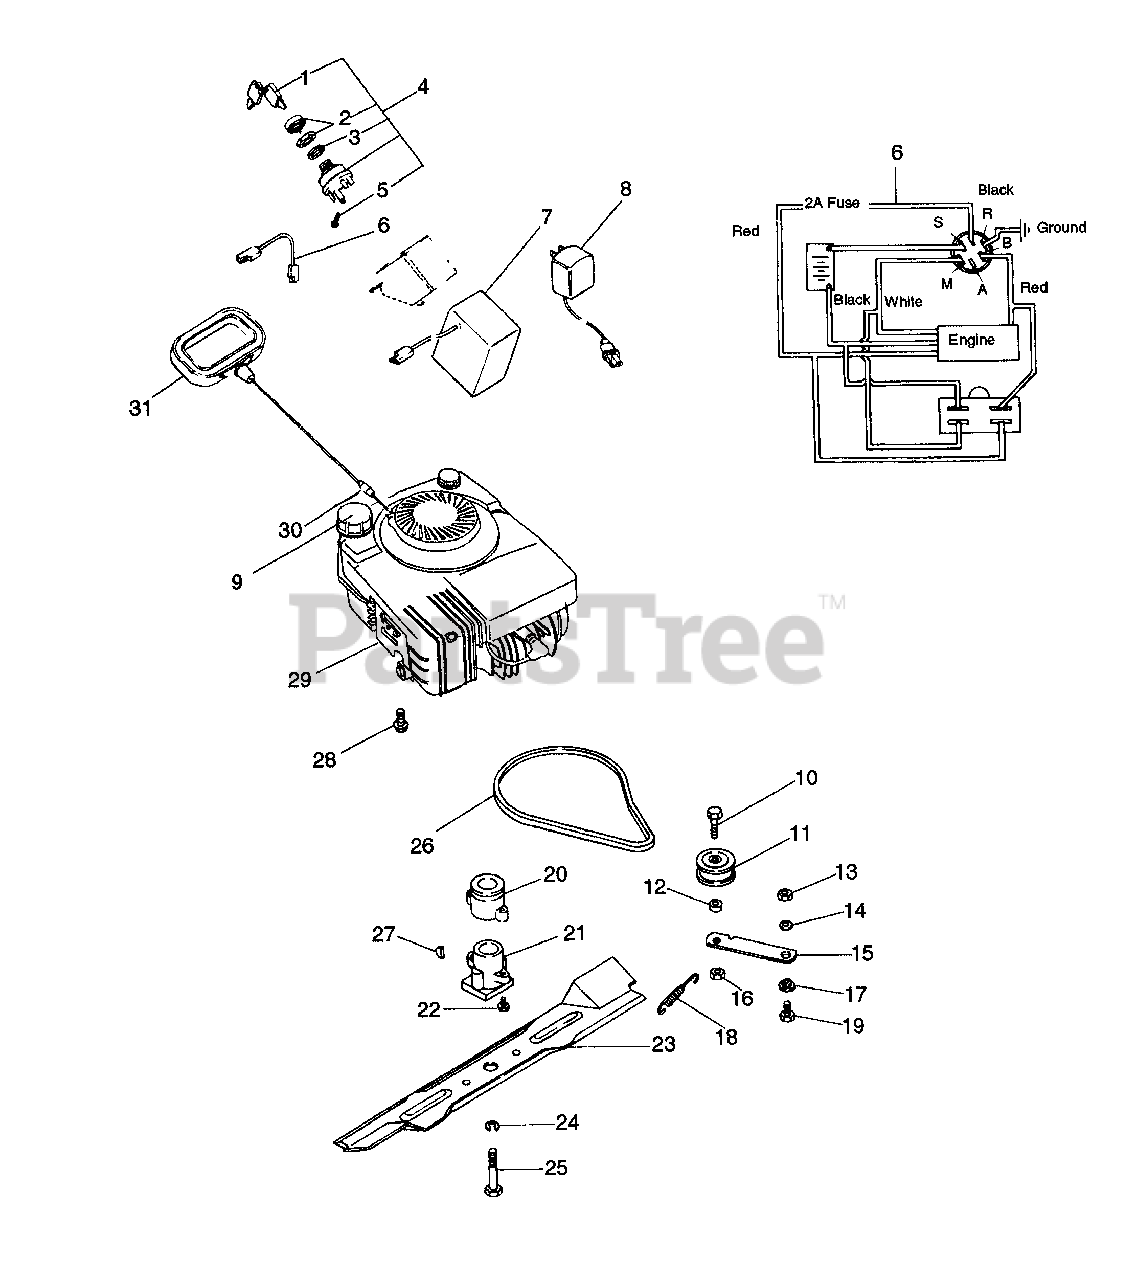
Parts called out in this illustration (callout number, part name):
1	KEY SET
2	NUT-PANEL .625-32 GRECO
2	CAP - IGNITION SWITCH
2	NUT .812-20 PL
3	WSHR-LK-INT .625X.045 PL
3	WSHR-LK-INT .813X.020 PL
4	KEY SWITCH
5	SCR-MCH 10-32X.32 SLRH PL
6	WIRE HARNESS
7	BATTERY
8	BATTERY CHARGER
9	FUEL CAP
10	BLT-HEX .44-14X1.25 PL GR2
11	IDLER-FLAT 1.75 X .47
12	SPACER .52 X .45 X .34
13	NUT-LK .312-18 GR A PL
14	WSHR-FL-STL .323X.625X.062 PL
15	IDLER ARM
16	NUT-LK .437-14 GR A PL
17	BSHG-FLG .325X.501X.250X1.120
18	SG-TENS .043X.44X3.31 WLD 5.8
19	BLT-HEX .31-18X.75 PL GR2
20	TRACTION DRIVE SHEAVE
21	BLADE ADAPTER
22	SCR-TAP 10-24X1.0 HWH PL TR
23	21" MOWER BLADE
24	WSHR-LK .375X.094 MED PL
25	BLT-HEX .38-24X2.00 PL GR5
26	V-BELT, 3L-COGGED
27	KEY-WDRF .156X.625X.25 SAE 6
28	SCR-TAP .375-16X1.0 HWH PL TR
29	Order Engine and Parts from Engine Manufacturers Dealer
29	ENGINE B/S 5HP. REC QUAN. I/C
29	ENGINE TEC 5.5HP RECOIL VECTOR
29	ENGINE TEC 5.5HP ELEC. VECTOR
29	ENGINE TEC 5.5HP BBC VECTOR
29	ENGINE B/S 5HP QUANTUM XTE
29	ENGINE TEC 5HP RECOIL TVS115
30	ROPE BULLET
31	HANDLE, RECOIL START
